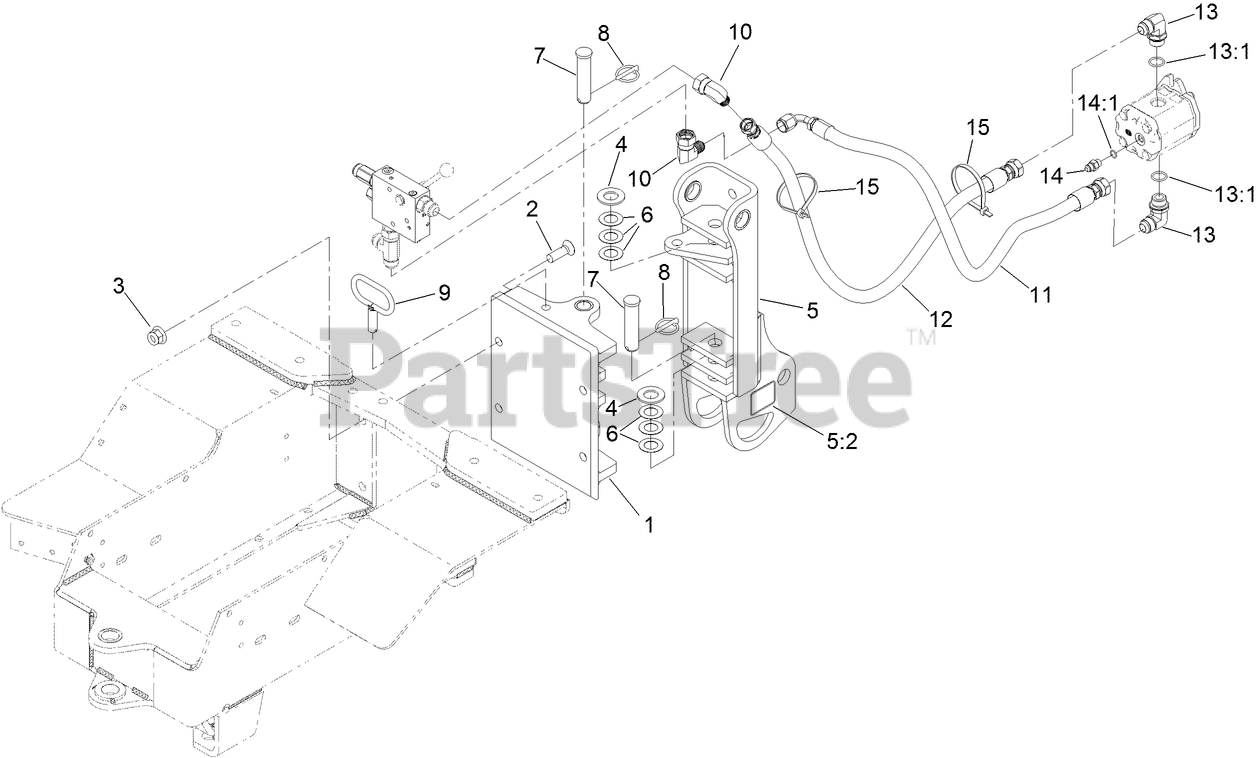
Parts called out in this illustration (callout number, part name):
1	SLIDE-QUICK ATTACH
2	SCREW-HSFH
3	NUT-HHF
4	WASHER-FLAT
5	PIVOT ASM
5:2	DECAL-TIE DOWN
6	WASHER-FLAT
7	PIN-PIVOT
8	KLIK PIN ASM
9	LOCK-SWING
10	FITTING-ELBOW, 90
11	HOSE ASM
12	HOSE ASM
13	FITTING-ELBOW, 90 DEG
13:1	O-RING
14	FITTING-STRAIGHT
14:1	O-RING
15	TIE-CABLE
